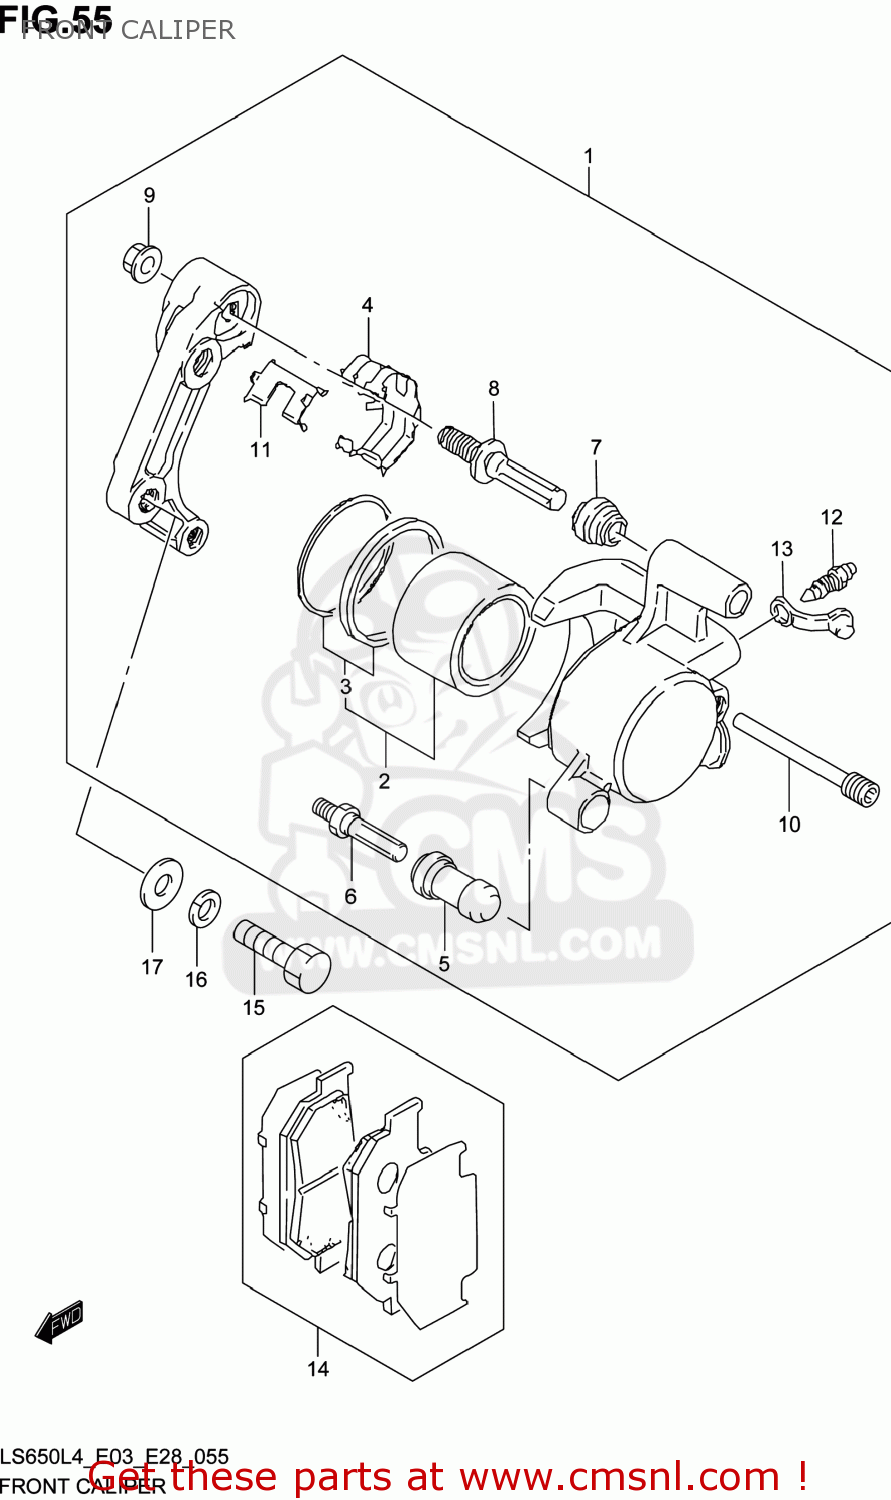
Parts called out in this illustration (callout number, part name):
1	CALIPER ASSY,FR
2	PISTON SET
3	SEAL SET,PISTON
4	SPRING
5	BOOT
6	BOLT
7	BOOT
8	PIN,SLIDE
9	NUT,SLIDE PIN
10	PIN,HANGER
11	RETAINER
12	BLEEDER
13	CAP,BLEEDER
14	PAD SET (NAS)
15	BOLT(10X38)
16	WASHER,LOCK
17	WASHER
